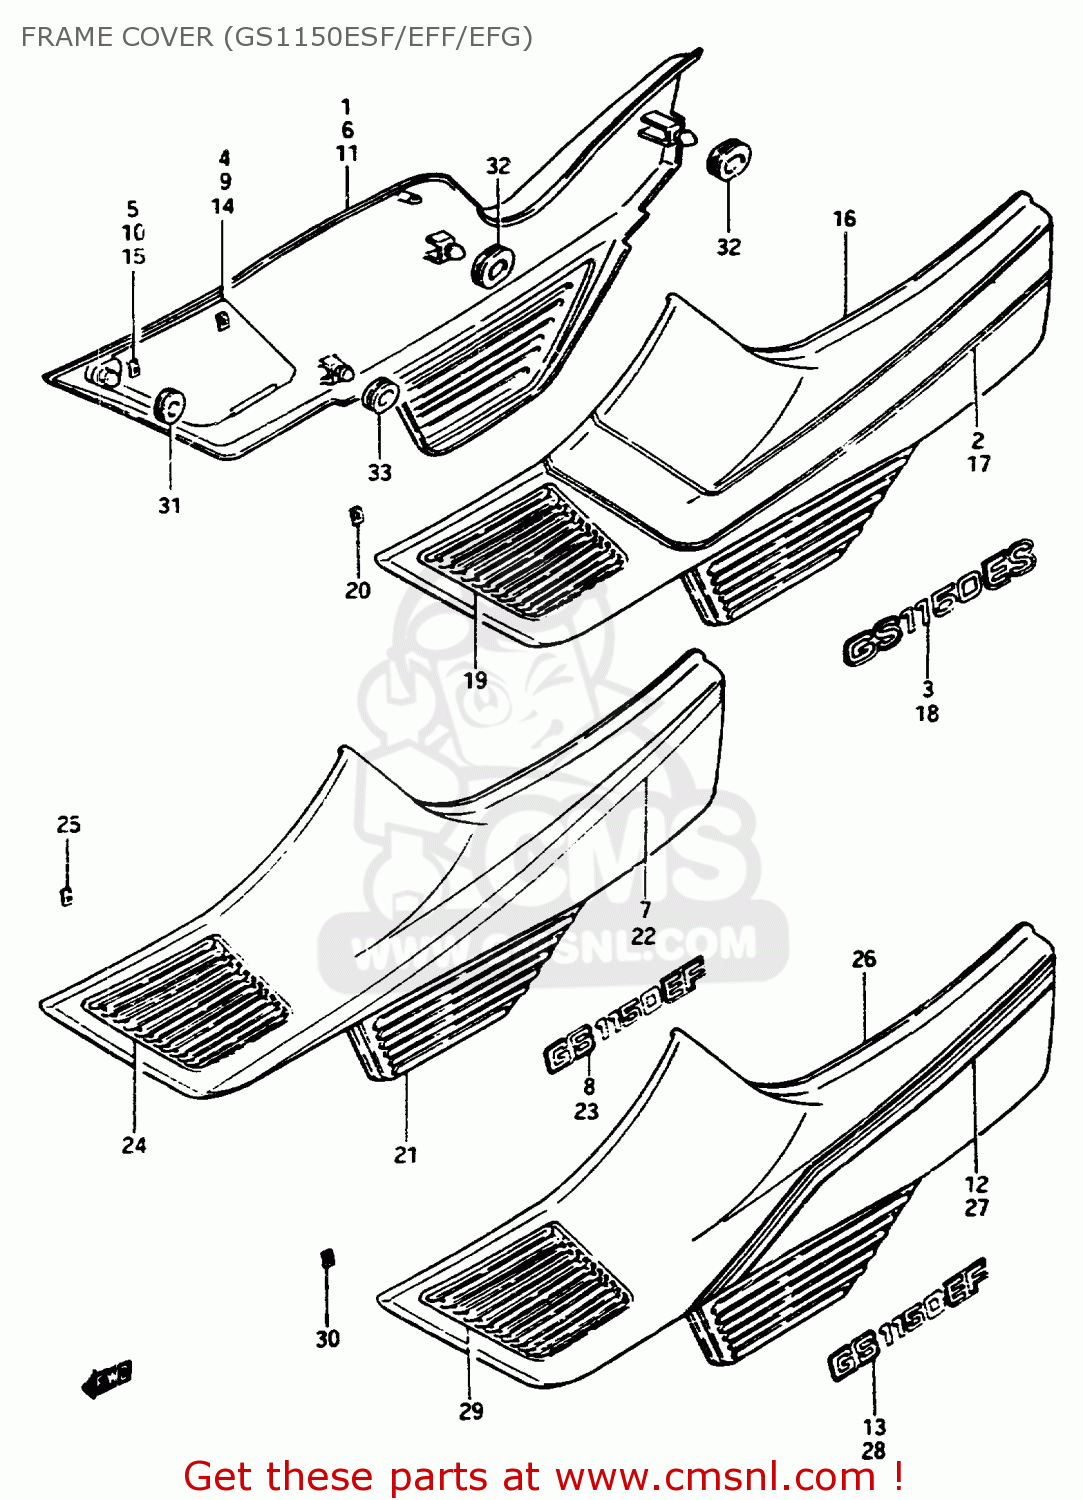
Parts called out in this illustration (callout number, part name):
1	COVER ASSEMBLY,FRAME BODY
2	TAPE SET,FRAME COVER
3	EMBLEM
4	COVER,FRAME,RIGHT NO.1
5	NUT
6	COVER, FRAME RH
7	TAPE SET,FRAME COVER,RIGHT
8	EMBLEM
9	COVER,FRAME,RIGHT NO.1
10	NUT
11	COVER, FRAME RH
12	TAPE SET, FRAME COVER RH
13	EMBLEM
14	COVER,FRAME,RIGHT NO.1
15	NUT
16	COVER, FRAME LH
17	TAPE,FRAME COVER
18	EMBLEM
19	COVER,FRAME,RIGHT NO.1
20	NUT
21	COVER, FRAME LH
22	TAPE SET,FRAME COVER,LEFT
23	EMBLEM
24	COVER,FRAME,RIGHT NO.1
25	NUT
26	COVER, FRAME LH
27	TAPE SET, FRAME COVER LH
28	EMBLEM
29	COVER,FRAME,RIGHT NO.1
30	NUT
31	CUSHION
32	CUSHION
33	CUSHION
